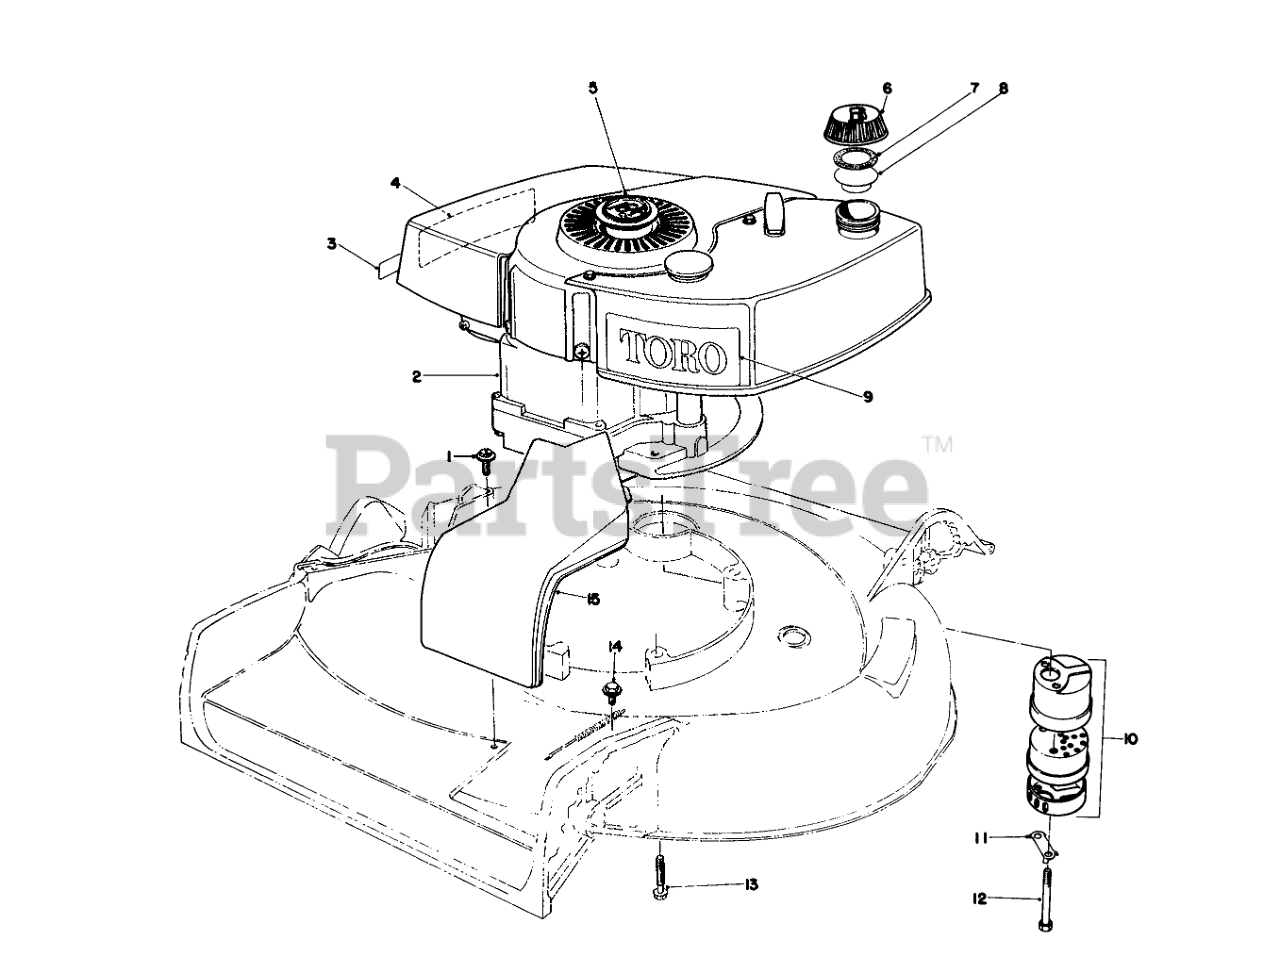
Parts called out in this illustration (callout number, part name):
1	SCREW
2	Engine
3	Decal-Primer Bulb
4	Decal Maintenance
5	Plug Button
6	Gas Cap Assembly (Incl. Ref. #7 & 8)
7	GASKET
8	GAS CAP BAFFLE
9	Decal Toro
10	Muffler (Incl. Ref. #11 & 12)
11	CLIP - LOCKING
12	SCREW-HH
13	3/8-16 X 2-3/4 CAPSCR
14	SCREW-HWHTF
15	Cover-Belt Drive
